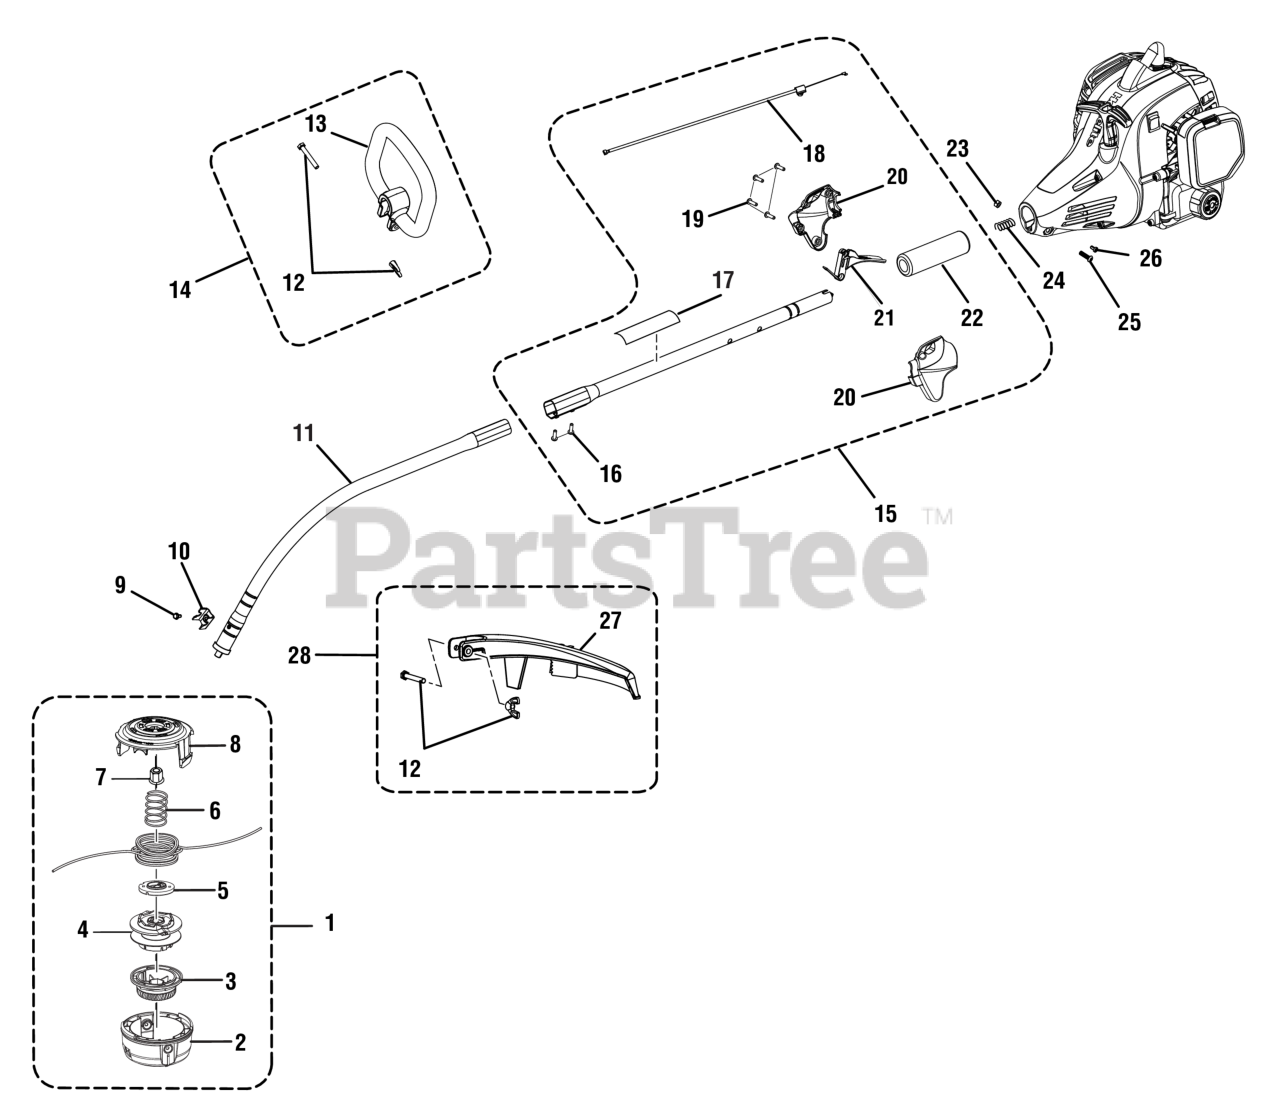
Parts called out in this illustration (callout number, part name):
1	Trimmer Head Assembly
2	Lower Housing
3	Bump Knob (Gray)
4	Spool Assembly
5	String Guide
6	Compression Spring
7	Flange Nut (M8)
8	Upper Housing
9	Screw (#10-32 x 3/8 in., Hex Washer Hd. S.T.)
11	Lower Boom Assembly
12	Fastener Parts Kit
13	Front Handle
14	Front Handle Assembly
15	Boom Assembly
16	Set Screw (M5 x 10 mm, Hex Soc. Hd.)
17	Icon Warning Label
18	Throttle Cable
19	Screw (M4 x 20 mm, T20 Torx Pan Hd. T.Fl.)
20	Trigger Handle Assembly
21	Throttle Trigger
22	Rubber Grip
23	Hex Nut (M6.3 x 1)
24	Compression Spring
25	Screw (M6 x 20 mm, T27 Torx Button Hd.)
26	Screw (M4 x 8 mm, T25 Torx Pan Hd. T.F.)
27	Grass Deflector
28	Grass Deflector Assembly
